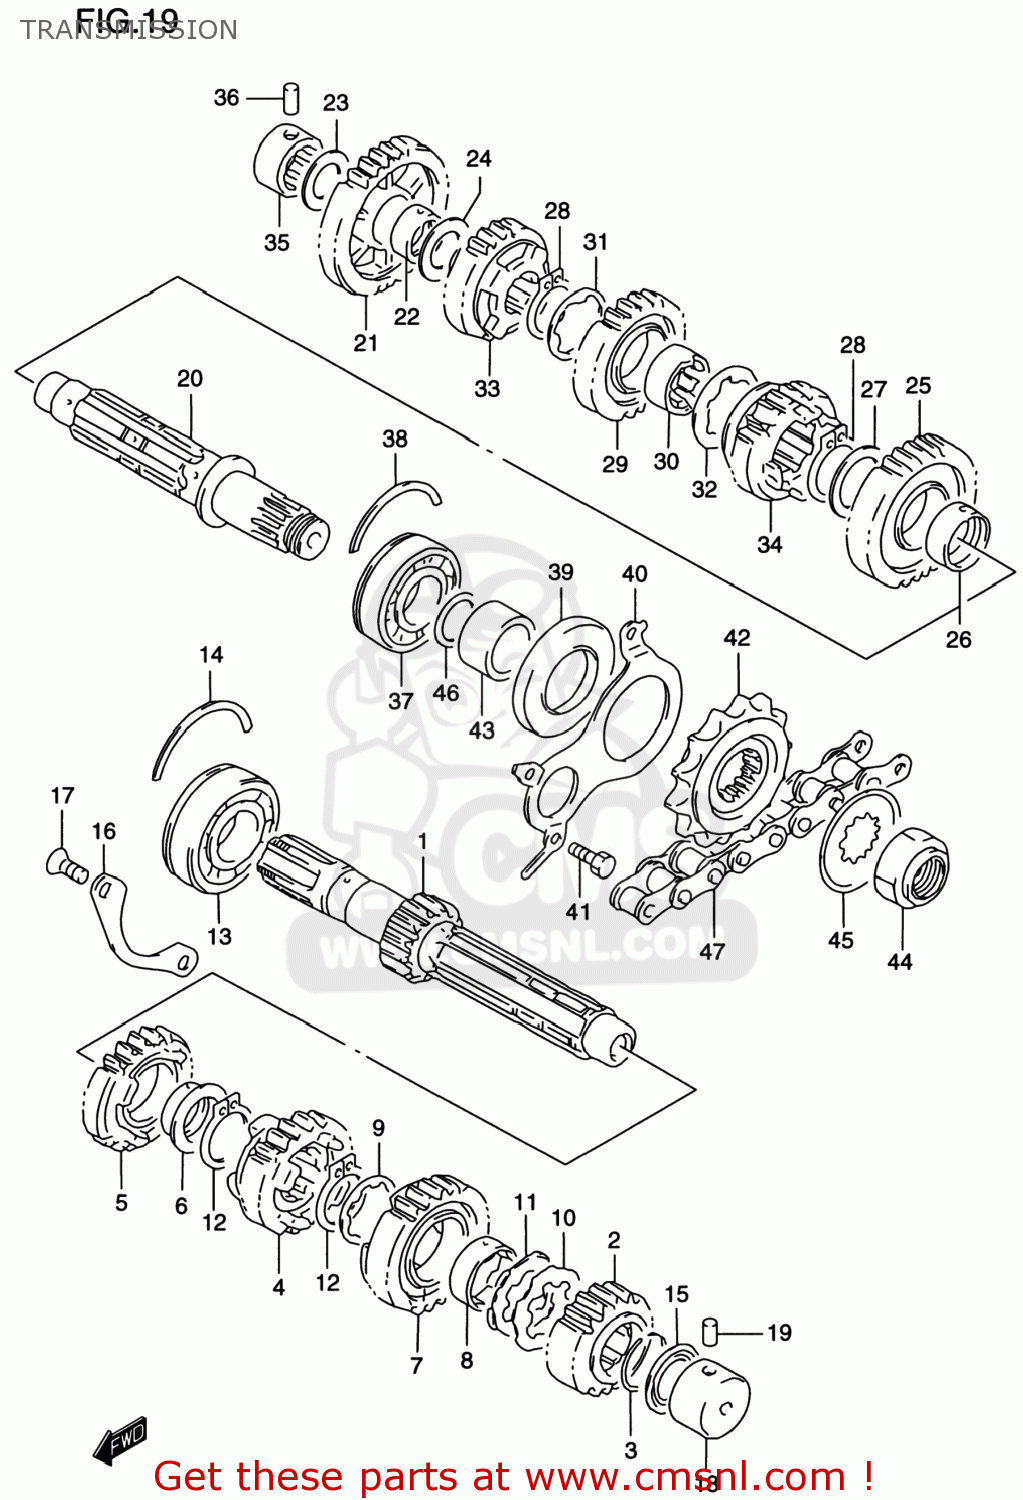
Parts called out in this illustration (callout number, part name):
1	SHAFT,COUNTER (NT:13)
2	GEAR,2ND DRIVE(NT:19)
3	CIRCLIP
4	GEAR,THIRD DRIVE (NT:20)
5	GEAR,FOURTH DRIVE (NT:22)
6	BUSHING
7	GEAR,FIFTH DRIVE (NT:23)
8	BUSH,5TH DRIVE GEAR
9	WASHER,LOCK
10	WASHER,LOCK
11	WASHER
12	RING,SNAP
13	BEARING(25X62X17)
14	C RING
15	SEAL,OIL(20X31.2X2.7)
16	RETAINER,CNTR SHAFT BEARING
17	SCREW
18	BEARING(20X34X17.5)
19	PIN
20	SHAFT,DRIVE
21	GEAR,FIRST DRIVEN (NT:31)
22	BUSHING
23	SHIM(20X34X1)
24	SHIM(22X34X1)
25	GEAR,2ND DRIVEN(NT:31)
26	BUSH(28X32X11)
27	SHIM(28X36X1)
28	CIRCLIP
29	GEAR,THIRD DRIVEN (NT:25)
30	BUSH,3RD DRIVEN GEAR
31	WASHER,LOCK
32	WASHER,LOCK
33	GEAR,FOURTH DRIVEN (NT:23)
34	GEAR,FIFTH DRIVEN (NT:21)
35	BEARING(20X34X20)
36	PIN
37	BEARING(25X62X21.6)
38	C RING
39	SEAL,OIL(34X62X6)
40	RETAINER,DRIVE SHAFT OIL SEAL
41	BOLT
42	SPROCKET,ENGINE(NT:15)
43	SPACER(25X34X19)
44	NUT
45	WASHER,LOCK
46	O RING(D:1,ID:24.5)
47	CHAIN ASSEMBLY,DRIVE RKGB5
